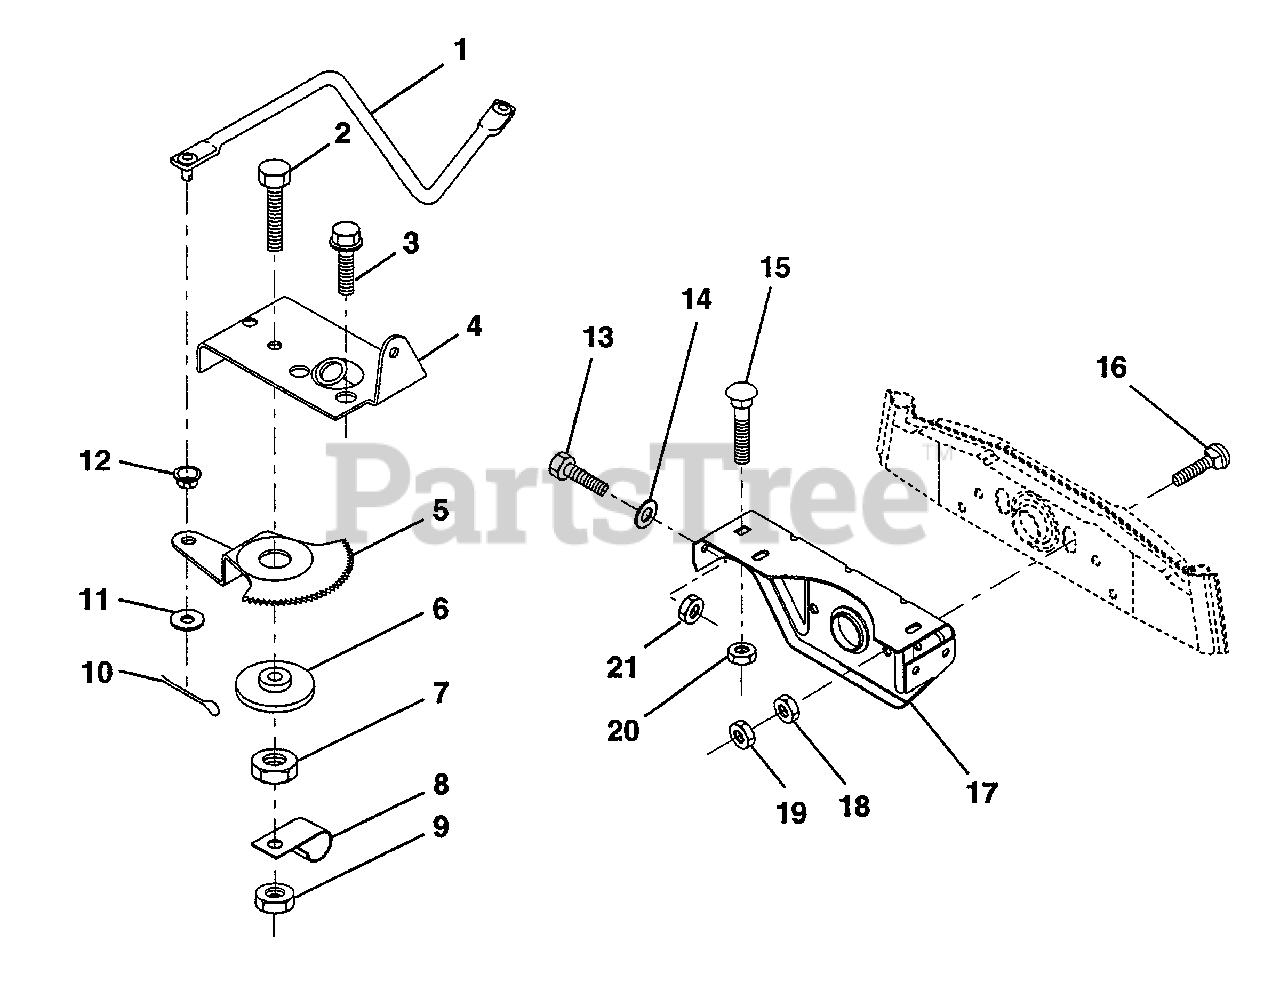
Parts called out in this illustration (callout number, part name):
1	Link, Drag
2	Bolt, Fin Hex 1/2-13 x 1-3/4
3	Screw, Hex Thrdrol 5/16-18 x 1/2
4	Plate, Steering Support
5	Gear, Sector
7	Nut, Heavy Hex Top Lock 1/2-13 UNC
8	Clip, Insulated
9	Nut, Crownlock 3/8-16
10	Pin, Cotter 1/8 x 3/4
11	Washer, 13/32 x 13/16 x 16 Ga.
13	Bolt, Hex Hd. 5/16-18 UNC x 1
14	Washer 11/32 x 7/8 x 16 Ga.
15	Bolt, Carriage 3/8-16 UNC x 3/4
16	Bolt, Carriage
17	Support, Front Axle
18	Nut, Fin Hex 3/8-16 UNC
19	Nut, Centerlock 3/8-16 UNC
20	Nut, Crownlock 3/8-16 UNC
21	Nut, Crownlock 5/16-18
